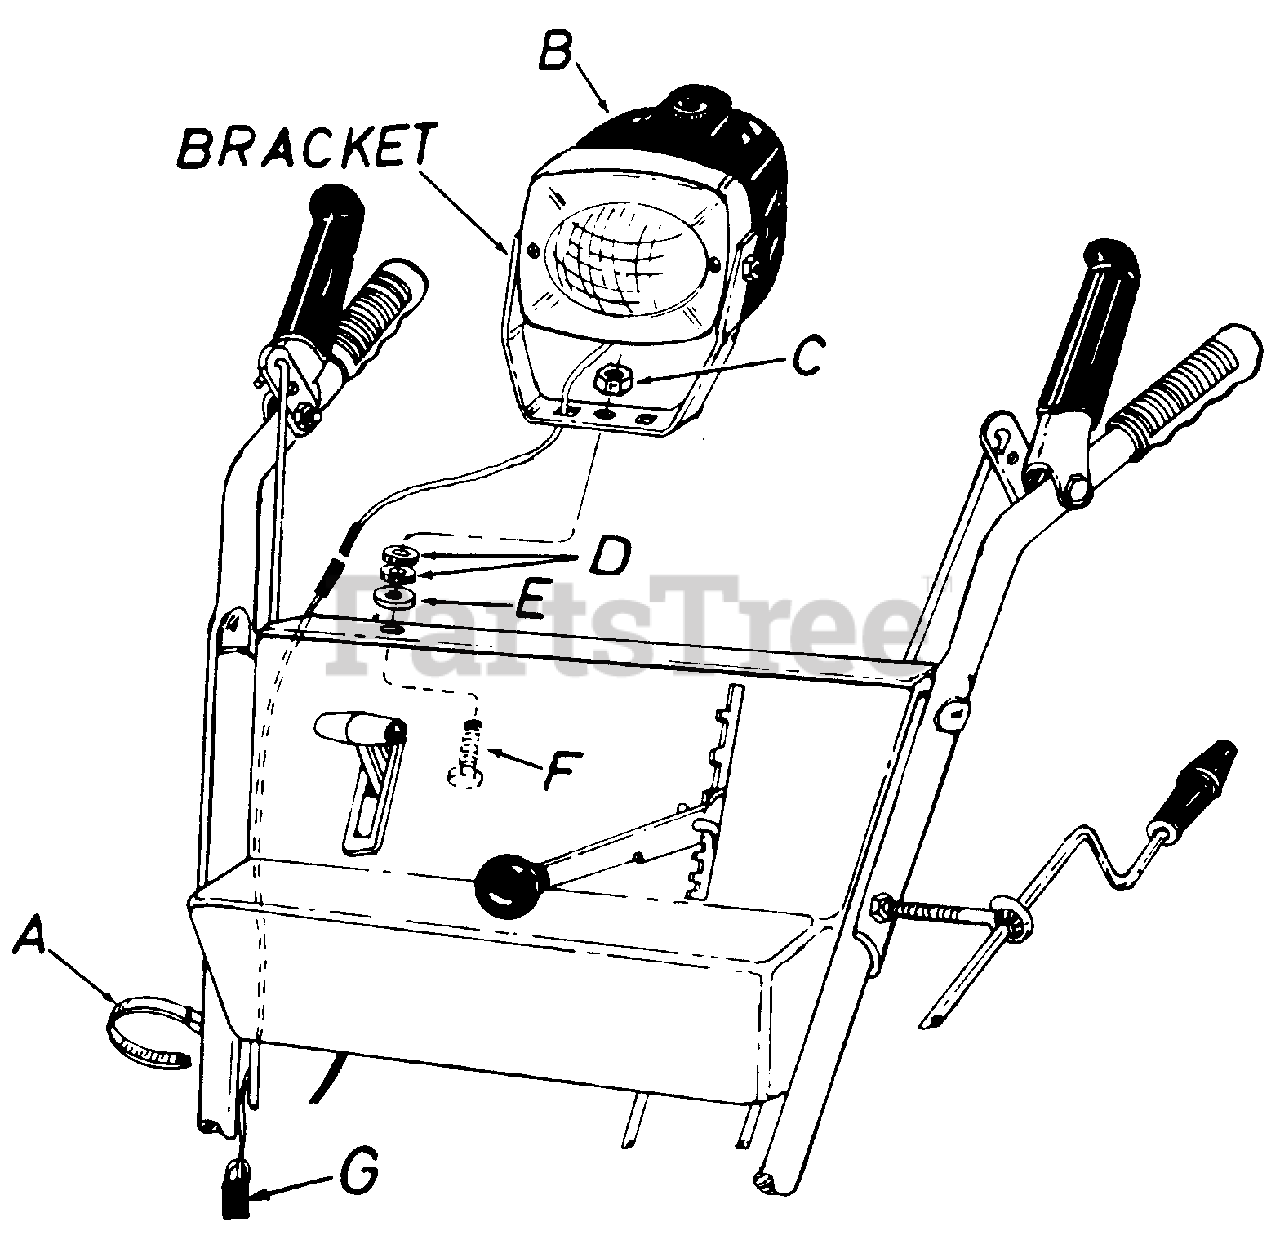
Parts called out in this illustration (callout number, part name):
A	Cable Ties
B	Head Lamp Ass'y. Comp.
C	Hex Cent. L-Nut 5/16-18 Thd.
D	Rubber Wash. .87" O.D. x .12 Thk.
E	Flat Wash. .34" I.D. x 1.12" O.D. x .12 Thk.
F	Hex Bolt 5/16-18 x 1.0" Lg.
G	Wire Harness
